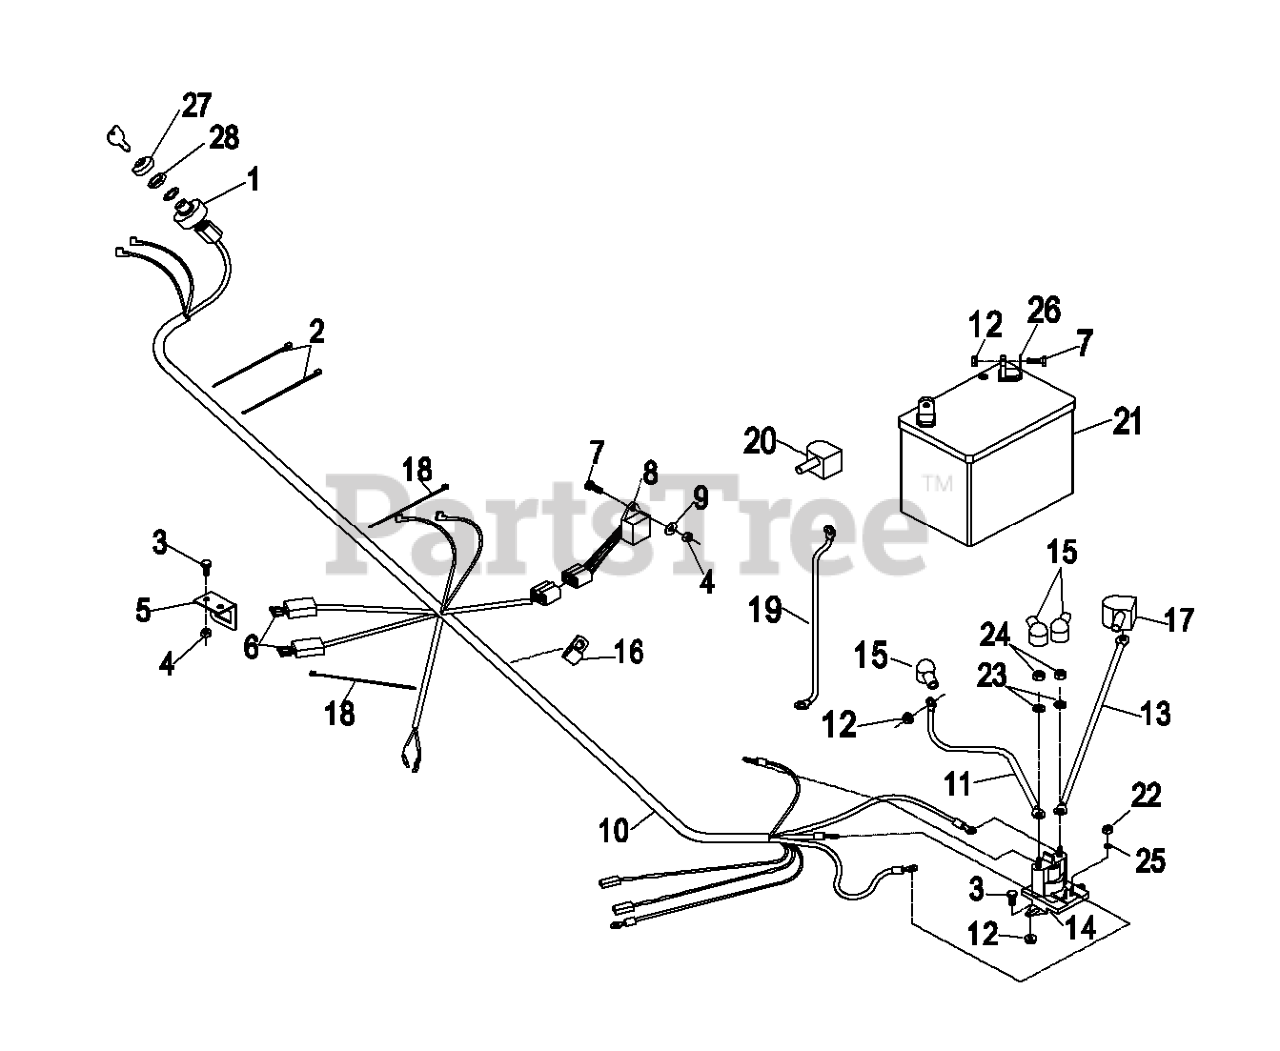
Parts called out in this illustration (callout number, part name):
1	SWITCH,IGNITION
2	TIE-PLASTIC
3	Screw, 1/4-20 X 5/8
4	NUT-LOCK, NI
5	BRACKET,FUSE
6	FUSE-BLADE TYPE, 20 AMP
7	SCREW-HH
8	MODULE-OPC NO TIME DELAY
9	WASHER-PLAIN
10	HARNESS,WIRING ELEC ST
15	INSULATOR-SOLENOID
16	CLIP-LOOM
18	TIE-CABLE
19	CABLE-BATTERY, NEGATIVE
20	INSULATOR, BATTERY -
22	NUT-HEX
23	WASHER-LOCK
24	NUT-JAM
25	WASHER-LOCK
26	WASHER-FLAT
27	SEAL-SWITCH, IGNITION
28	NUT-SWITCH, IGNITION
